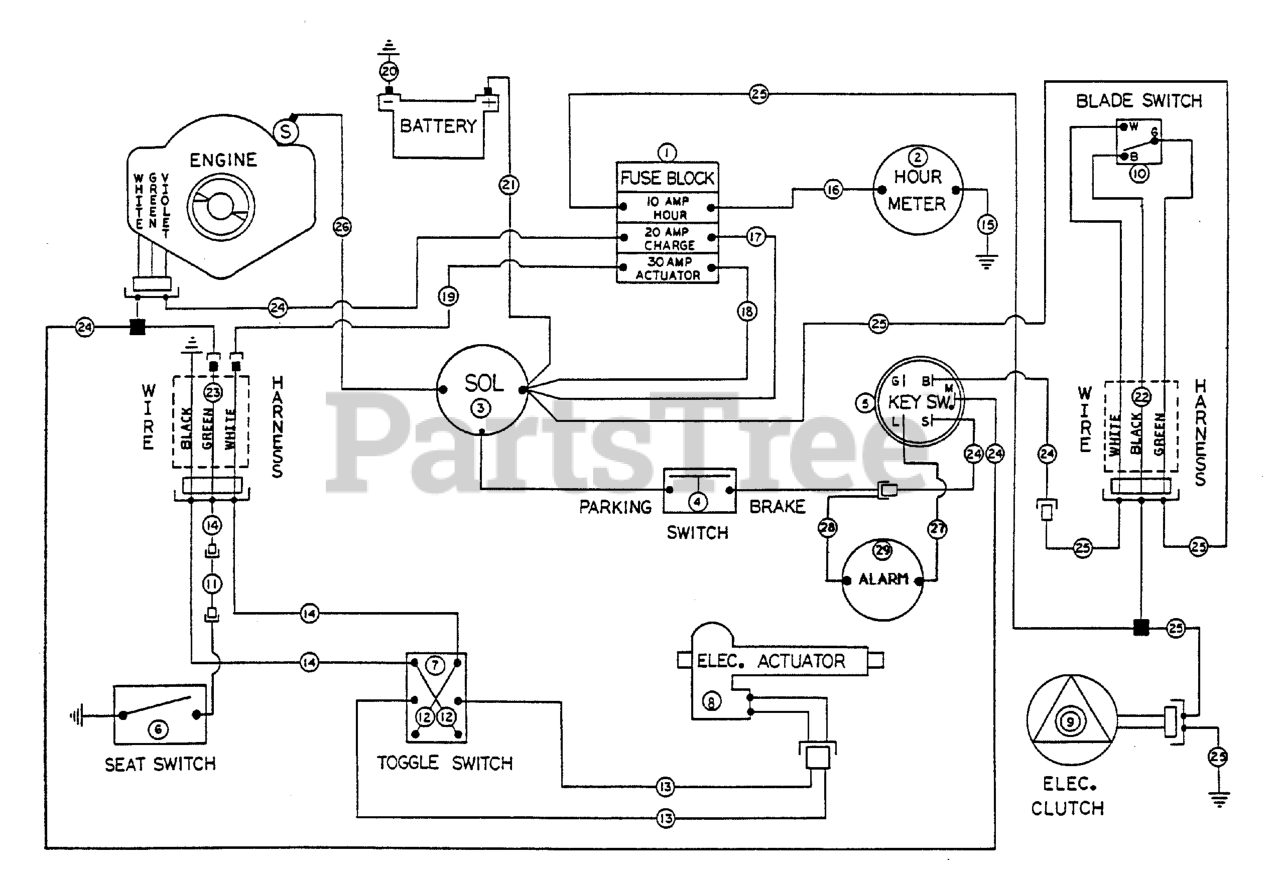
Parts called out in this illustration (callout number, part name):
1	Fuse Block
1	10 Amp Fuse
1	20 Amp Fuse
1	30 Amp Fuse
2	HOUR METER
3	SOLENOID, Starter
4	Parking Brake Switch Assembly
5	SWITCH, Ignition
6	Seat Switch Assembly
7	Toggle Switch
8	Electric Actuator
9	CLUTCH, Electric, 1" Shaft
10	Toggle Switch
11	Green Alpha Cable to Seat Switch
12	Red Corner to Corner Toggle Switch
13	Toggle Switch to Actuator Harness
14	Actuator Switch to Alpha Cable Harness
15	Blue (-) Hour Meter to Ground
16	Blue Fuse Block to Hour Meter (+)
17	Red Fuse Block to Solenoid
18	White Fuse Block to Solenoid
19	White Alpha Cable to Fuse Block
20	Negative Battery Cable
21	Positive Battery Cable
22	Alpha Cable - Electric Clutch
23	Alpha Cable - Electric Actuator
24	Key Switch / Charge Harness
25	Electric Clutch / Alpha Cable Harness
26	Solenoid to Starter
27	Key Switch to Alarm (Supplied w/ Alarm)
28	Alarm to Parking Brake (Supplied w/ Alarm)
29	Alarm
